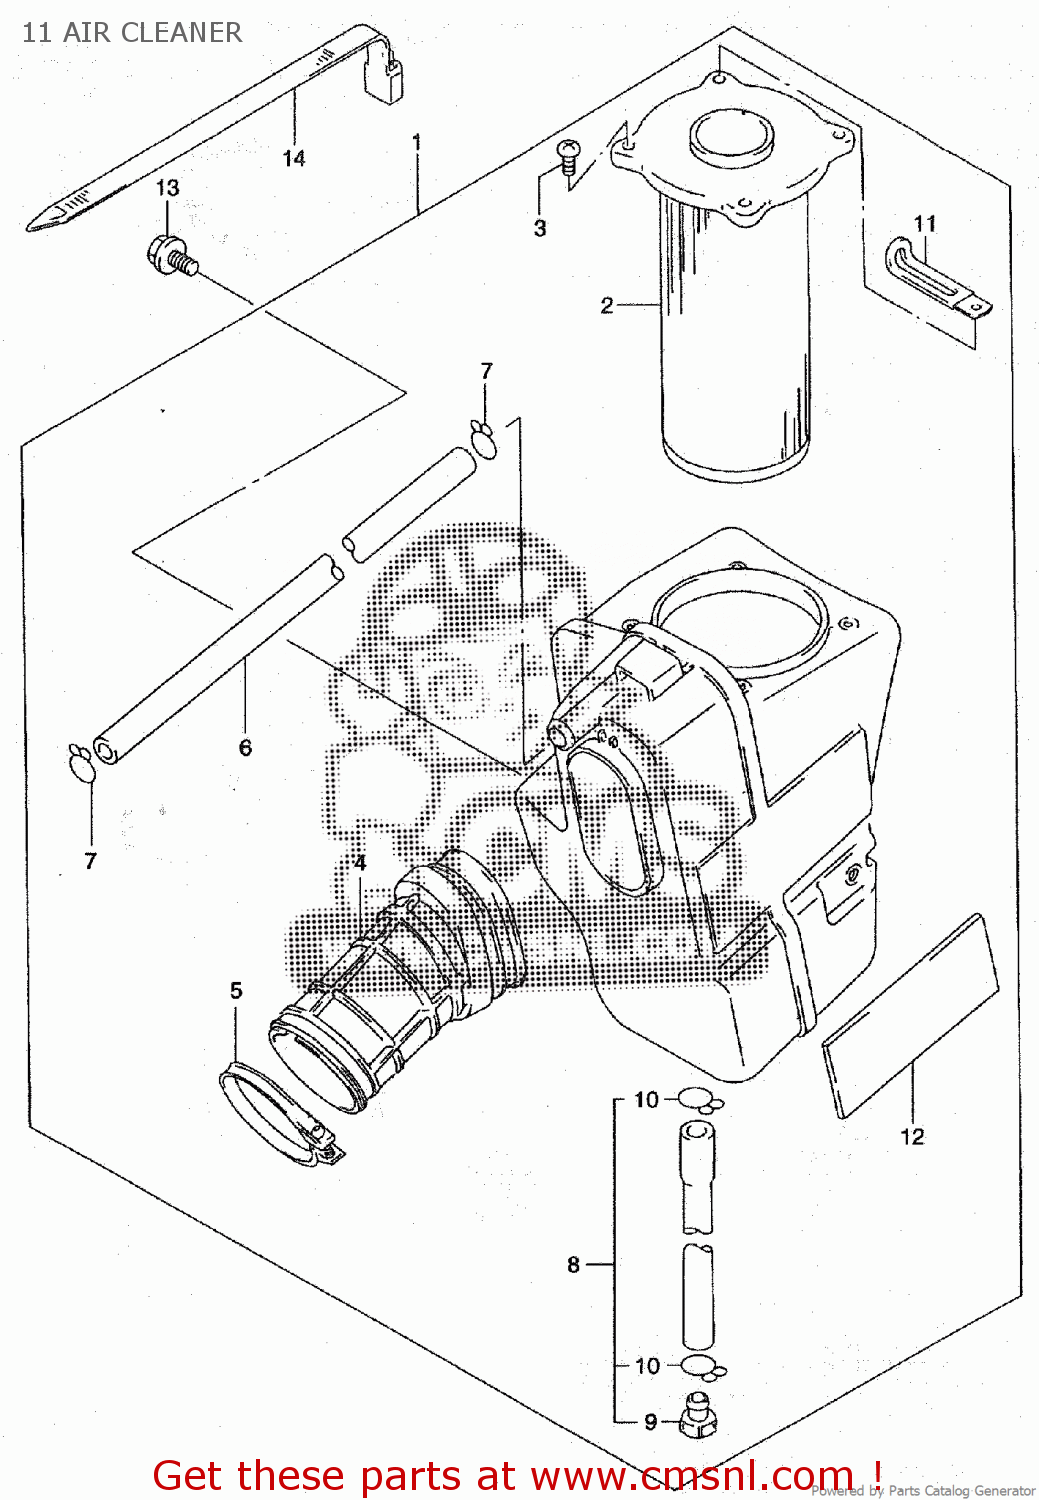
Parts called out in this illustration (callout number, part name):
2	FILTER
3	SCREW
5	CLAMP
7	CLIP
8	TUBE,DRAIN
9	PLUG
10	CLIP
11	CLAMP(L:65)
13	BOLT
14	CLAMP(L:165)
